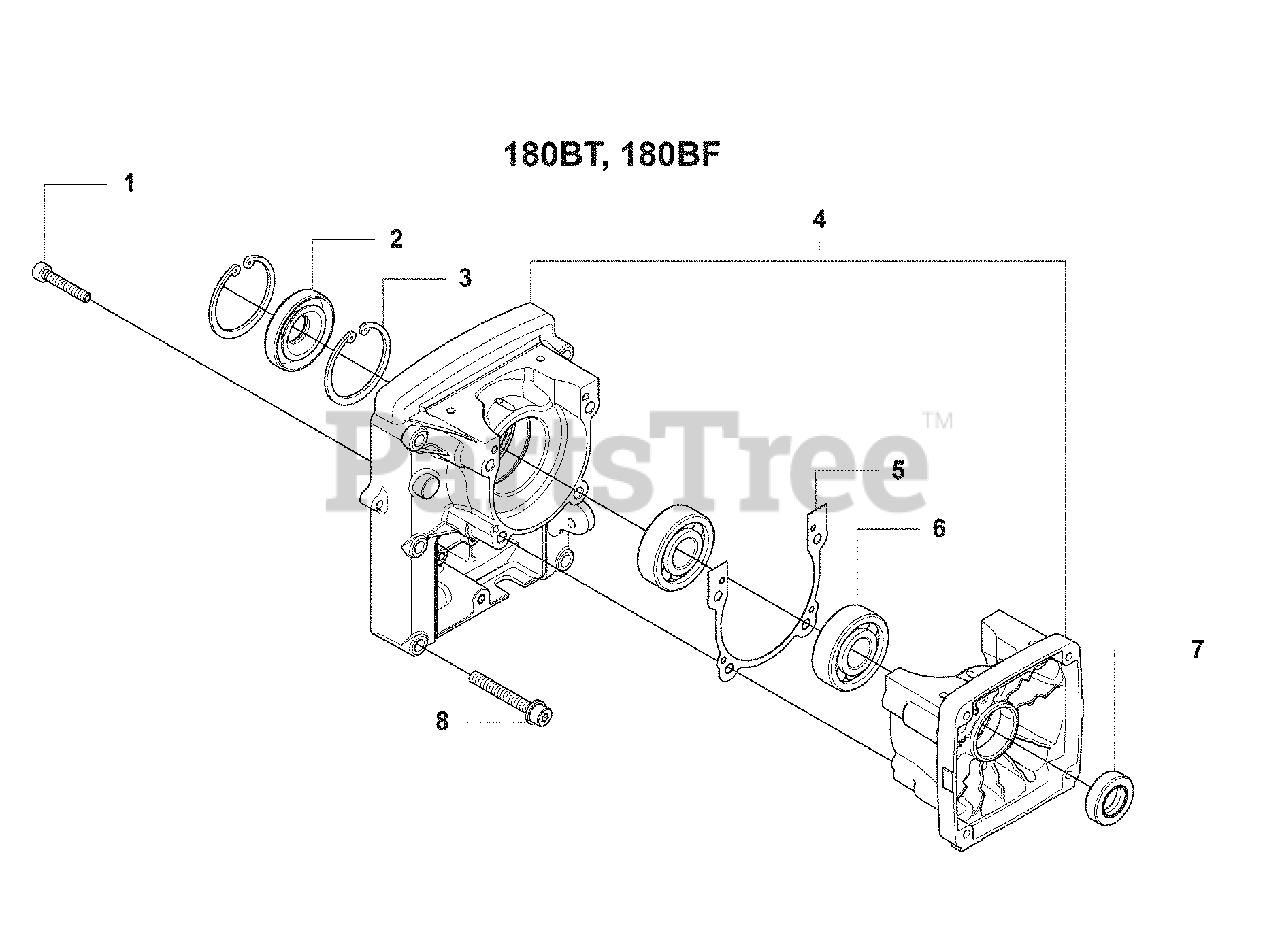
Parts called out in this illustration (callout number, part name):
1	Bolt
2	Seal
3	Snap Ring
4	CRANKCASE-C
5	Gasket
6	Ball Bearing
7	Seal
8	Bolt
